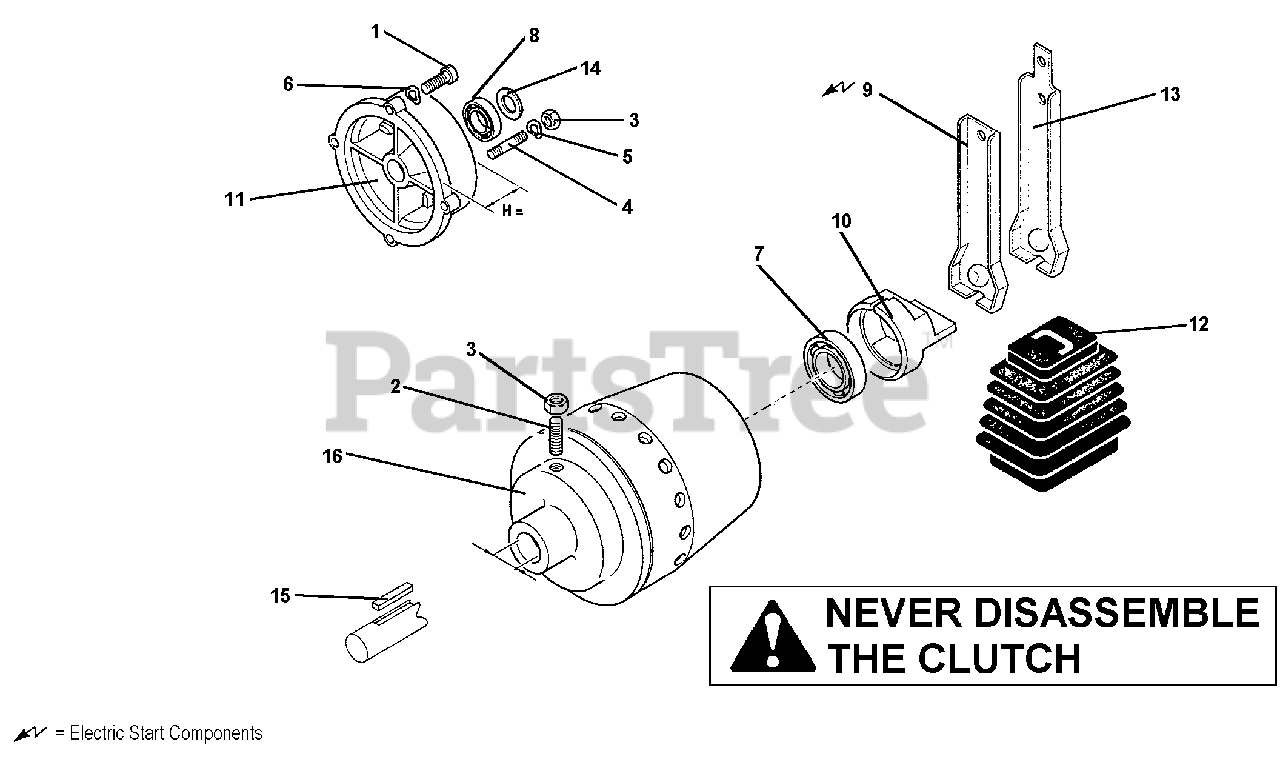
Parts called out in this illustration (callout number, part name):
1	SCREW 3/8X1"
2	SCREW M8X30
4	STUD,M8X40X14X14
5	WASHER, WAVE
6	WASHER, WAVE
7	BEARING,M17X40X12
8	BEARING,30X55X13
9	CLUTCH LEVER, ELECTRIC STA
10	CONE PUSHER
12A	BOOT, RECOIL START
12B	BOOT, ELECTRIC START
13	LEVER, RECOIL START
